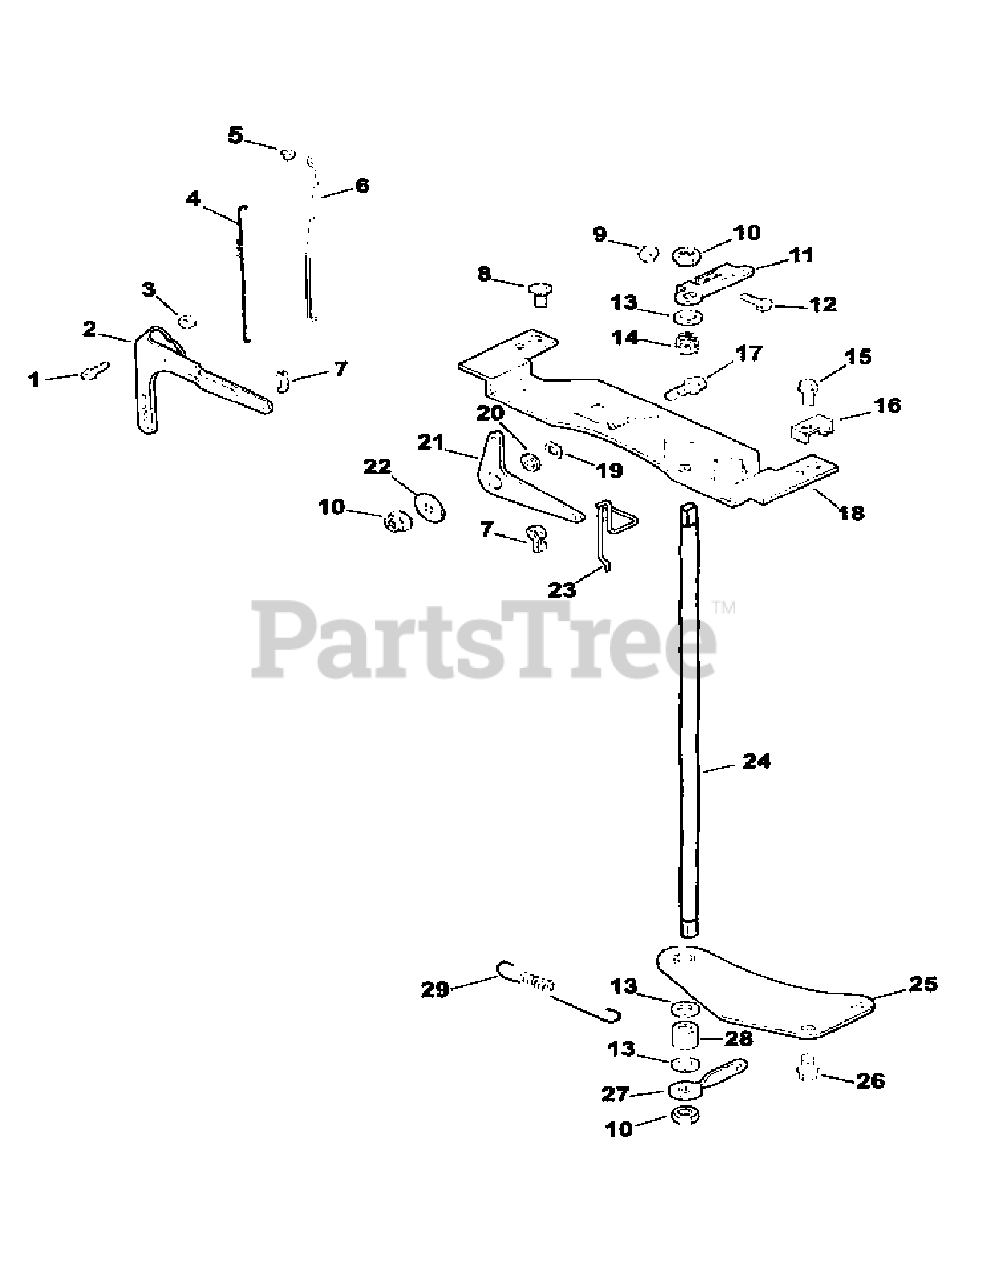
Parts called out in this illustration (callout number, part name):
1	Carriage Bolt (M6 x 1.0 x 25)
2	Governor Lever
3	Hex Flange Nut (M6 x 1.0)
4	Linkage Spring
5	Linkage Retaining Bushing
6	Throttle Linkage
7	Throttle Linkage Bushing
8	Phillips Head Screw (11-16 x 3/4")
9	Hex Nut (M4 x .7)
10	Hex Lock Nut (M6 x 1.0)
11	Throttle Control Lever
12	Hex Cap Screw (M4 x .7 x 25)
13	Plain Washer (1/4")
14	Throttle Shaft Spring
15	Hex Flange Screw (M5 x .8 x 16)
16	Cable Clamp
17	Hex Flange Screw (M6 x 1.0 x 16)
18	Control Bracket
19	Spring Washer (3/8")
21	Choke Lever
22	Plain Washer (1/4")
23	Choke Linkage
24	Throttle Shaft
25	Throttle Shaft Bracket
26	Hex Flange Screw (M6 x 1.0 x 40)
27	Throttle Control Lever
29	Governor Spring
